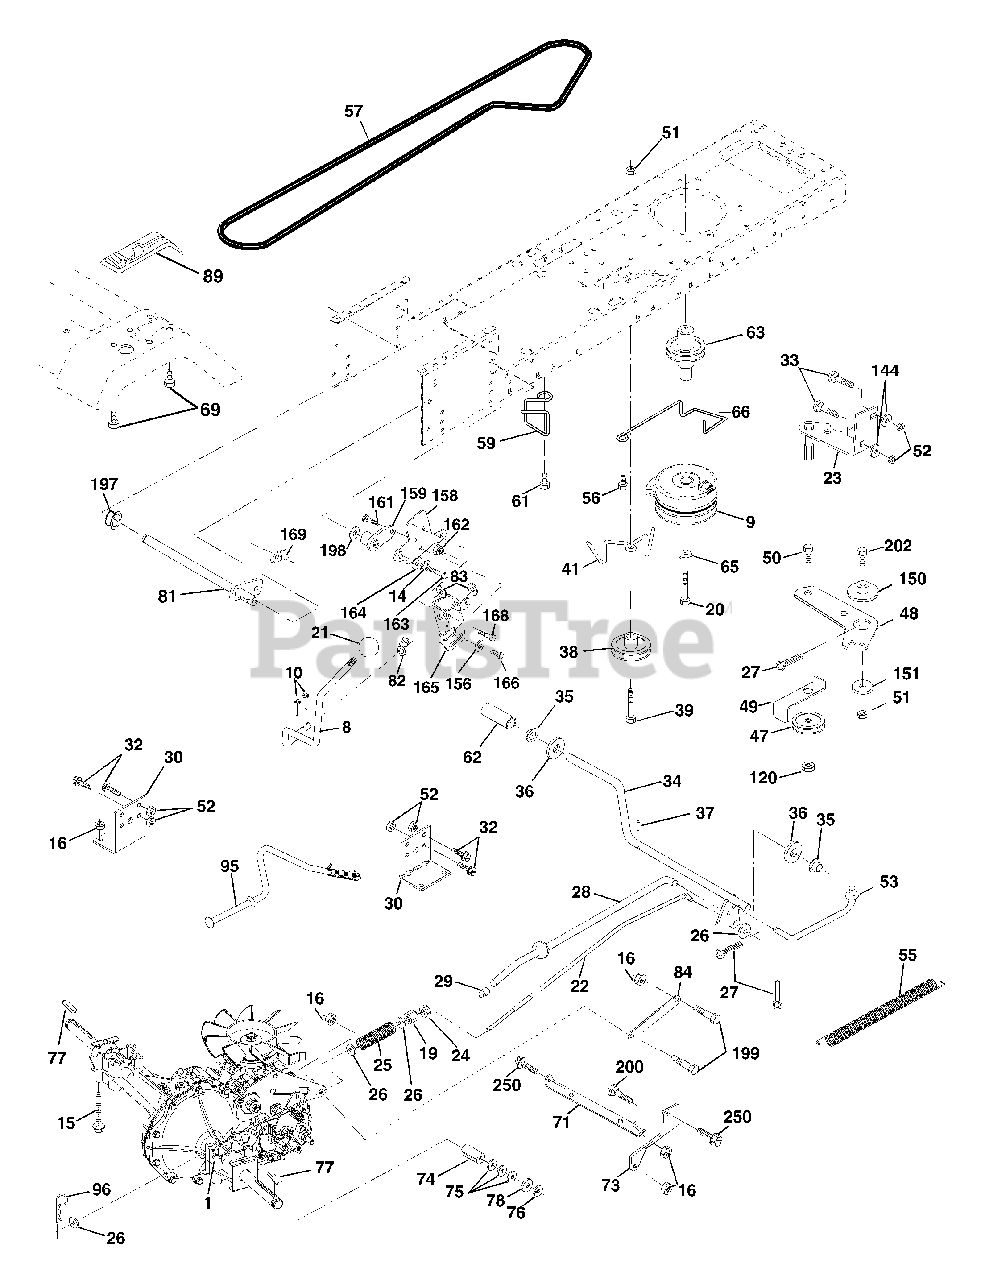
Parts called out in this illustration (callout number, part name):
8	Rod Shift Fender Adjust LT
9	Clutch Electric
10	Pin Cotter 1/8 x 1 CAD
14	Washer Lock Hvy Helical
15	Bolt Hex 5/16-18 Gr. 5
16	Nut Lock Hex W/Ins. 5/16-18 Unc P
19	Nut Lock Hex W/Ins 3/8-16 Unc
20	Bolt, Hex 7/16-20 x 4-1/4 Ga. 5
21	Knob Deluxe 1/2-13 UNC BLK/BLK
22	Rod, Brake Hydro
23	Bracket Asm. Anti-Rot EVX
24	Nut Hex Jam 3/8-16 UNC
25	Spring, Brake Rod
26	Washer
27	Pin Cotter 1/8 x 3/4 CAD.
28	Rod, Parking Brake
29	Cap,Parking Brake
30	Bracket, Transaxle
32	Bolt Hex Hd 5/16-18 Unc x 3/4
33	Bolt Carriage 5/16-18 UNC x 3/4
34	Shaft, Foot Pedal
35	Bearing, Nylon
37	Pin, Roll
38	Pulley, Idler, Composite
39	Bolt
41	Keeper, Belt Idler
47	Pulley, Idler, V-Groove Plastic
48	Bellcrank Clutch Grnd Drv Stl
49	Retainer, Belt Style Spring
50	Bolt Hex Hd 3/8-16 Unc x 1-1/2
52	Nut Crown Lock 5/16-18
53	Link, Clutch
55	Spring, Return, Clutch
56	Screw 3/8-16 x 1 1/4
57	V-Belt, Ground Drive
59	Keeper, Center Span
61	Screw 3/8-16 x .875
62	Cover, Pedal
63	Pulley, Engine
65	Washer Lock Hvy HLCL Spr 7/16
66	Keeper Belt Engine
69	Screw Hex Wsh Hi-Lo 1/4-1/2 Unc
71	Strap Torque Lh
73	Strap Torque Rh
74	Spacer, Axle
75	Washer 25/32 x 1-1/4 x 16 Ga.
77	Key, Square
78	Washer 25/32 x 1-5/8 x 16 Ga.
81	Shaft Asm Cross Tapered
82	Spring Torsion
83	Washer 17/32 x 3/4 x 16 Ga.
84	Link Transaxle
89	Console, Hydro
95	Control Asm. Bypass Hydro
96	Retainer Spring 1" Zinc/Cad
120	Nut Lock Flg. 3/8-16
144	Washer 11/32 x 5/8 x 16 Ga.
150	Bushing Bellcrank Grd Drive
151	Washer 13/32 x 2 x 10 Ga.
156	Washer Srrted 5/16 ID X 1 X .125
158	Bracket Shift Mount
159	Hub Tapered Flange Shift LT
161	Bolt Rdhd Sqnk 1/4-20 x 3/4 Gr. 5
162	Nut Crownlock 1/4-20 Unc
163	Bolt Hex Fin 1/4-20 Unc x 1 Gr. 5
164	Washer 5/8 x .281 x 10 Ga.
165	Bracket Pivot Lever
166	Screw 5/16-18 x 5/8
168	Bolt Shoulder 5/16-18 x .561
169	Plate Fastening LT
197	Nyliner Snap-In 5/8" ID
198	Washer Nyl 7/8ID x .105 Hyd
199	Bolt Shoulder 5/16-18 Unc
200	Bolt Rdhd Sqnk 5/16-18 Unc x 1
250	Screw 3/8-16 x .75
